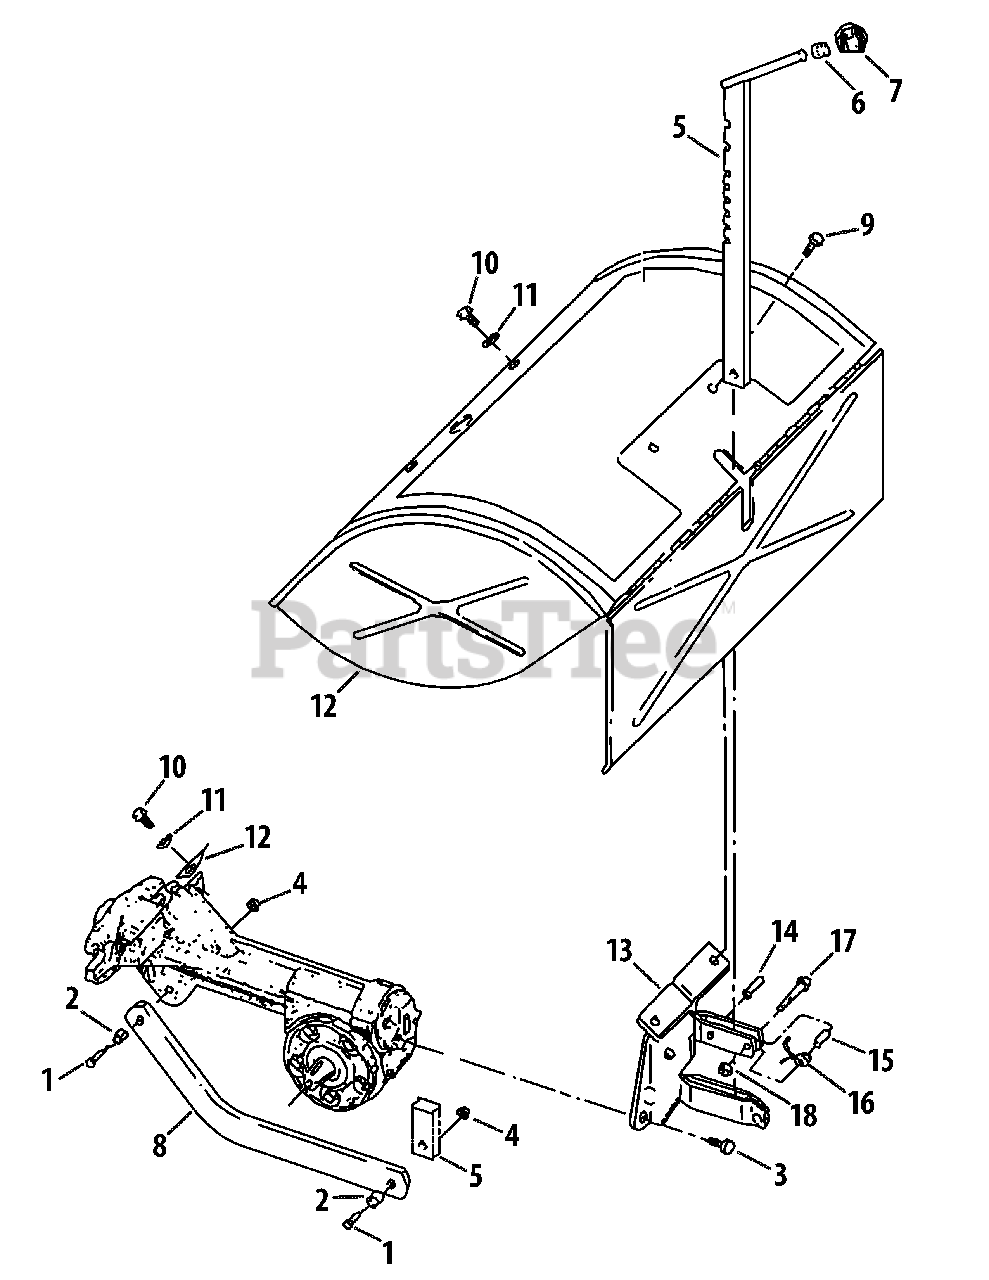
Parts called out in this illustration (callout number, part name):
1	Hex Bolt, 3/8-16 x 1-1/4
2	Bushing Spacer, .5 x .375 x .3
3	Hex Flange Bolt, 5/16-18 x .625
4	Flangelock Nut, 3/8-16
5	Depth Regulator
6	Retaining Ring
7	Depth Regulator Knob
8	Depth Regulator Bar Drag
9	Thread-forming Screw, 1/4-20 x 1/2
10	Hex Flange Bolt, 5/16-18
11	Washer, 1.12 x .34 x .06
13	Hood Bracket
14	Roll Pin (Spirol), 1/4 x 1
15	Split Spacer
17	Hex Bolt, 1/4-20 x 1
18	Locknut, 1/4-20
